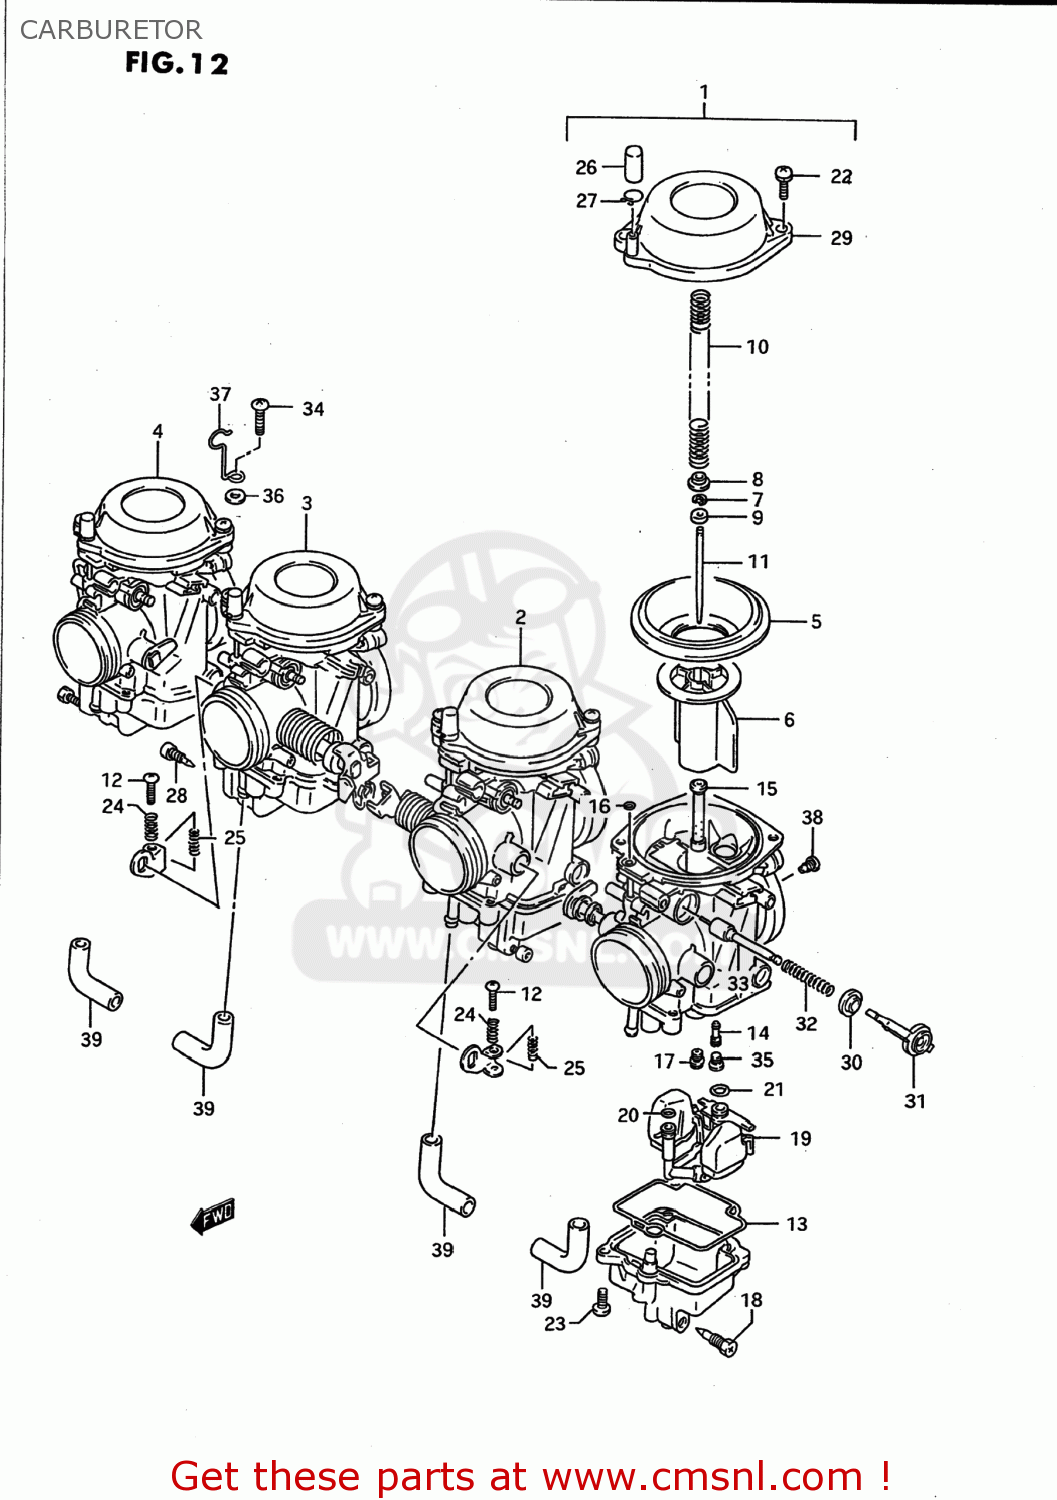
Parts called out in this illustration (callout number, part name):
1	CARBURETOR ASSEMBLY
2	CARBURETOR ASSEMBLY
3	CARBURETOR ASSEMBLY
4	CARBURETOR ASSEMBLY
5	DIAPHRAGM
6	VALVE,PISTON
7	CLIP,NEEDLE
8	RING
9	RING
10	SPRING
11	NEEDLE,JET
12	SCREW
13	GASKET,FLOAT CHAMBER (NAS)
14	JET,PILOT(32.5)
15	JET,NEEDLE (Y-1)
16	O RING
17	JET,MAIN(105)
18	PLUG,DRAIN
19	FLOAT/NEEDLE VALVE ASSEMBLY
20	O RING
21	O-RING,NEEDLE VALVE
22	SCREW
23	SCREW
24	SPRING
25	SPRING
26	CAP
27	CLIP
28	SCREW,DRAIN
29	COVER,DIAPHRAGM
30	CAP,STARTER
31	HOLDER,GUIDE
32	SPRING
33	PLUNGER ASSEMBLY
34	SCREW
35	PLUG
36	WASHER
37	CLIP
38	JET,AIR
39	HOSE
